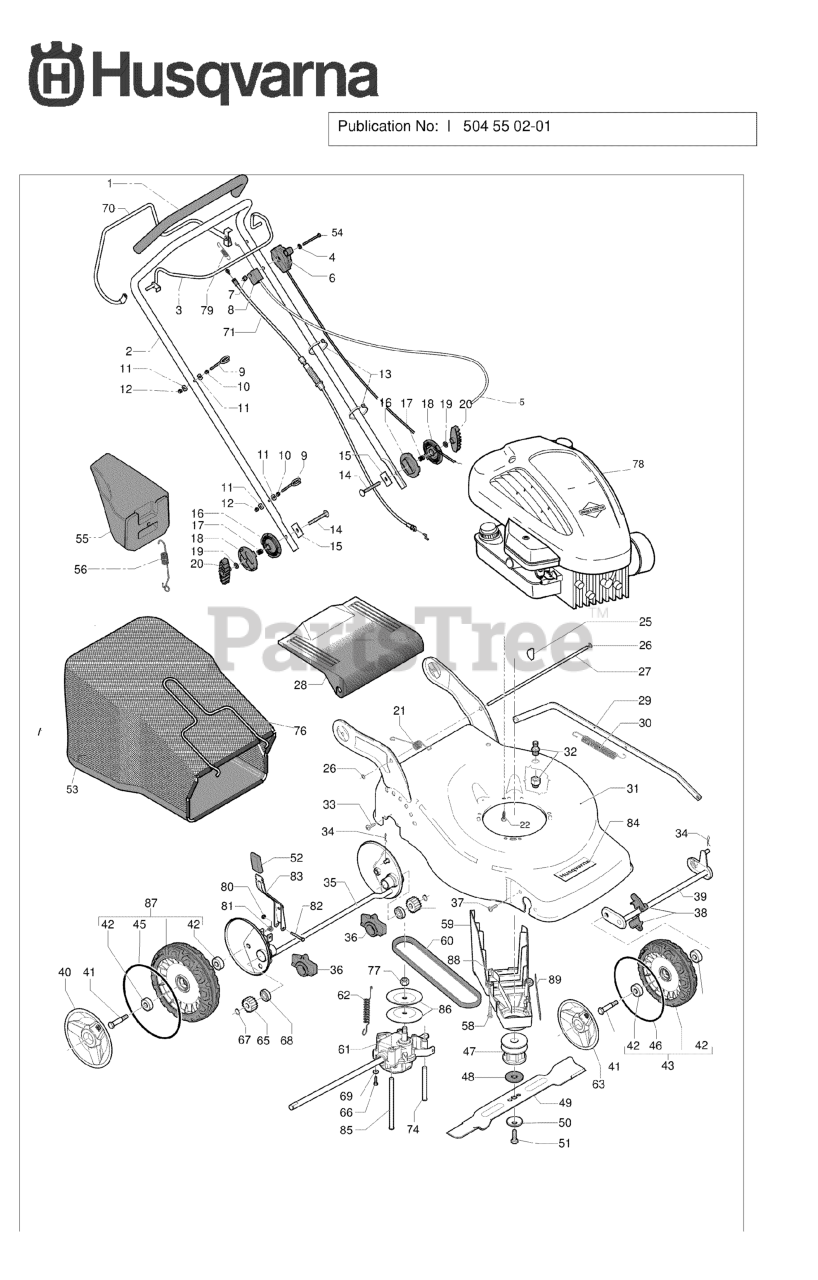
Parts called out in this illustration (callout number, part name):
5	BRAKE WIRE
35	REAR AXLE REAR AXLE WELDED FOR
49	MOWER BLADE COMBI
83	LIFTING LEVER ASSY FOR REAR AX
